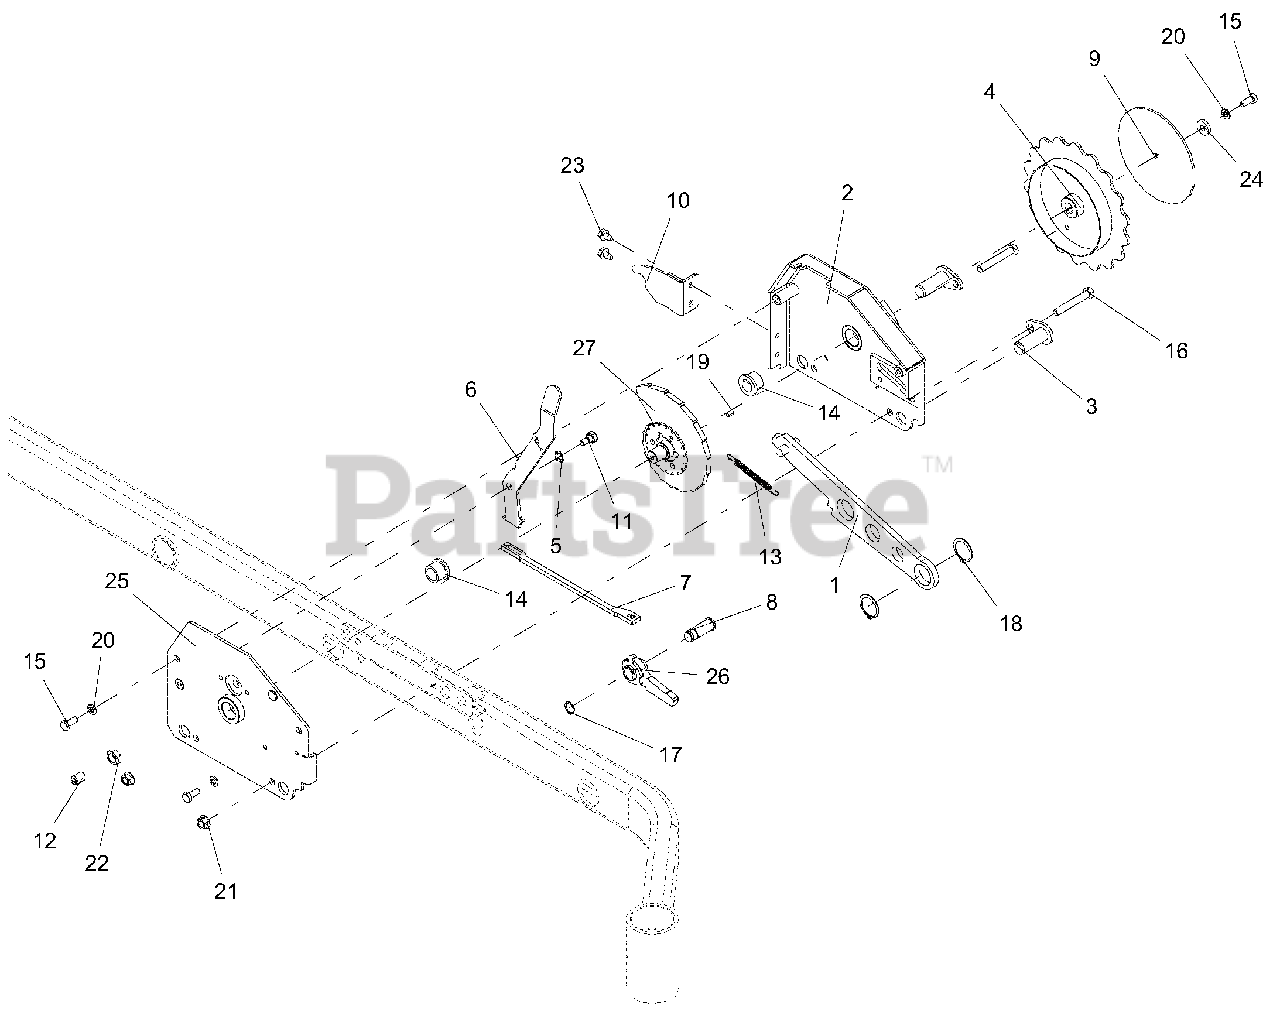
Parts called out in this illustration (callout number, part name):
1	WLDMT, HOC LINK-BLACK
2	WLDMT, HOC INNER-RED
3	WLDMT, PIN
4	WLDMT, DIAL, HOC
5	WAVE WASHER .390X.655X.110
6	LEVER, TRANSPORT LOCK-BLACK
7	LINK, TRANSPORT LOCK
8	PIN, CLEVIS .625 SNAP RING
9	PLATE, DIAL-RED
10	GUARD, DECK LIFT
11	BOLT, SHLDR .38-16 x .437 HEX YZ
12	BALL SPRING PLUNGER, .500-13
13	SPRG, EXTENSION
14	BUSHING, .750 X 1.00 X .750
15	BLT-HEX .31-18X.75 GR5 YWZC
16	BLT-HEX .38-16X2.50 GR5 YWZC
17	RG-RTNG-EXT .625x.050
18	RG-RTNG-EXT 1.25x.050
19	KEY-SQ .188X.188X.375
20	WSHR-LK .31X.078 REG YWZC
21	NUT, LK-CTR-FLG .38-16 YWZC
22	NUT, JAM .500-13 YWZC
23	SCR-TAP .31-18X.50 HWH TR YWZ
24	WSHR-FL-STL .328X.87X.179 YWZC
25	WLDMT, HOC OUTER-RED
26	WLDMT, LOCK PAWL
27	WLDMT, CAM HOC
